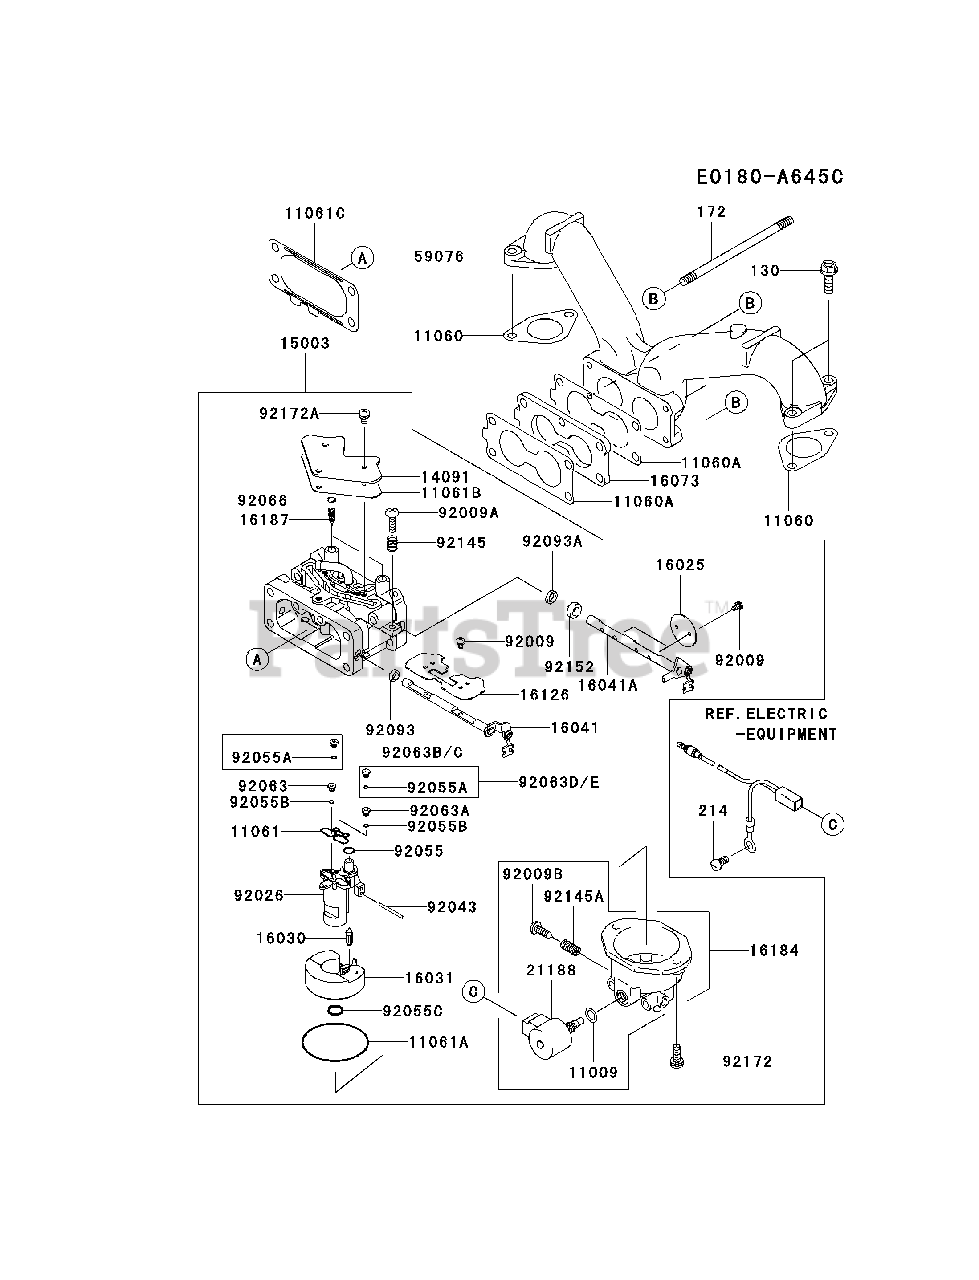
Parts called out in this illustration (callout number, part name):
130	BOLT-FLANGED,6X20
172	BOLT-STUD,6X105
214	SCREW-PAN+-,5X10
